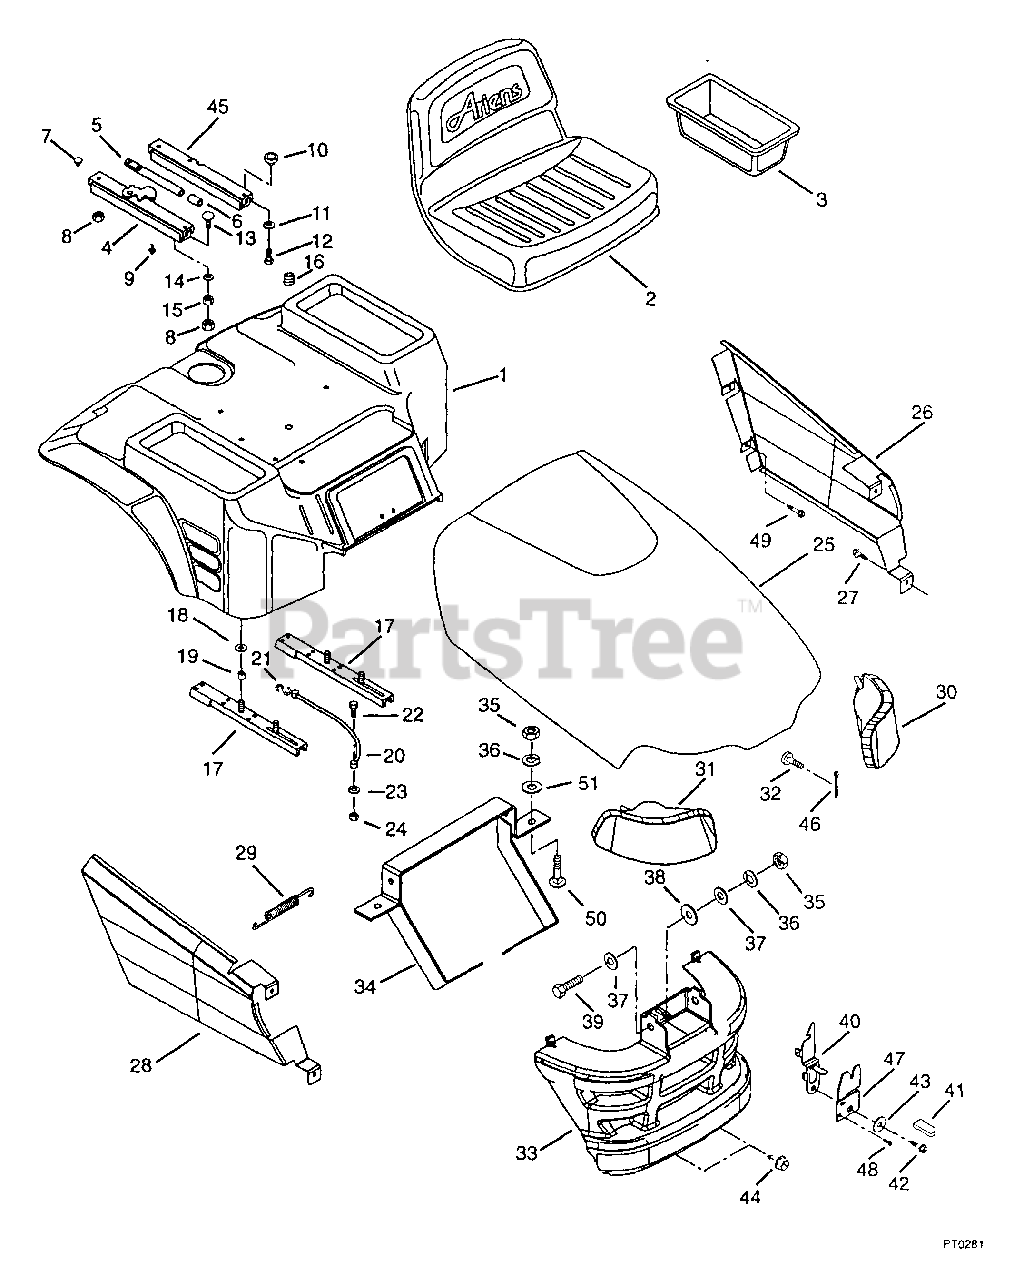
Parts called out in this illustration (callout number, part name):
1	REAR DECK
2	SEAT V-580
4	SEAT SLIDE R H
5	SEAT SLIDE HANDLE
7	SCR-CAP BTHD.31-18X.50 GR5 YZ
8	NUT-LK .312-18 GR A PL
9	NUT-LK 10-24 NY PL
10	SEAT SLIDE SPACER
11	WSHR-LK-EXT .313X.030 PL
12	SCR-MCH .31-18X1.00 CRRH PL
13	SCR-CAP BTHD.31-18X.875 GR5 PK
14	WSHR-LK .312X.097 PL HVY
15	NUT-HEX .312-18
16	GROMMET
17	SEAT SUPPORT
18	WSHR-FL-STL .390X.750X.125 PL
19	SPACER .380X.503X.281
22	SCR .25-20X.75 TS PH PL
23	WSHR-LK .250X.077 HVY PL
24	NUT-HEX .250-20 PL
26	SIDE PANEL- LH
27	SCR-TAP 12-16X.500 HI-LOTPHBL
28	SIDE PANEL- RH
29	SG-TENS .035X.45X2.75 WLD 3.5
30	HEADLIGHT- LH
31	HEADLIGHT- RH
32	PIN, CLEVIS .243/.248X1.50 YWZ
33	GRILLE
34	MOUNT - GRILLE
35	NUT-HEX .312-18
36	WSHR-LK .312X.097 PL HVY
37	WSHR-FL-STL .328X1.0X.094 PL
38	WSHR-FL-NYL .390X1.000X.062
39	BLT-HEX .31-18X1.00 PL GR5
40	HOOD LATCH
41	GRIP .062 X .375 X 1.000 RE
42	SCR-TAP 12-24X.50 HWH TR BLACK
43	WSHR-FL-STL .281X1.250X.048 BL
44	SCR-TAP .312-18X.50 HWH TR BL
45	SEAT SLIDE L H
46	PIN-COTR .09X.75 PL
47	LOCATOR, HOOD
48	SCR-TAP 10-12X.50 CRPH PL A BL
49	SCR-TAP 10-12X.62 CRPH PL A
50	BLT-RDHDSQSHNK .38-16X1.00 PL
51	WSHR-FL-STL .438X1.0X.083 PL
